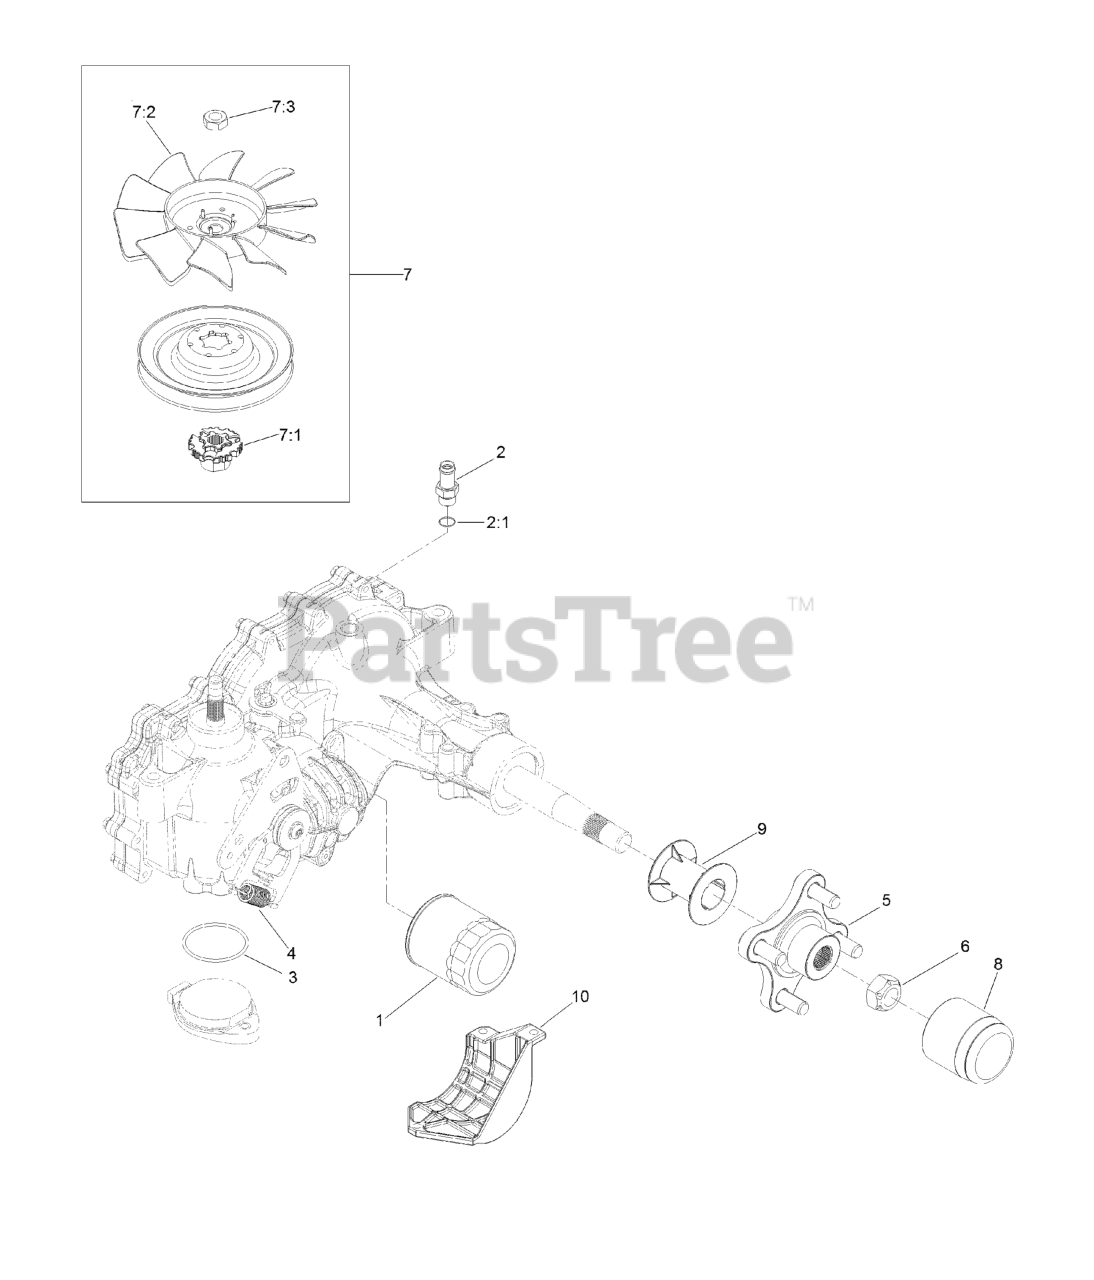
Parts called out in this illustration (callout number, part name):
1	ELEMENT-OIL FILTER, HYD
2	ADAPTER-STRAIGHT
2:1	O-RING
3	O RING-SEAL
4	SPRING-EXTENSION
5	HUB-OFFSET
6	NUT-HUB
7	FAN AND PULLEY KIT
7:1	HUB-FAN
8	CAP-AXLE, LONG
9	TUBE-AXLE
10	GUARD-FILTER, LH
